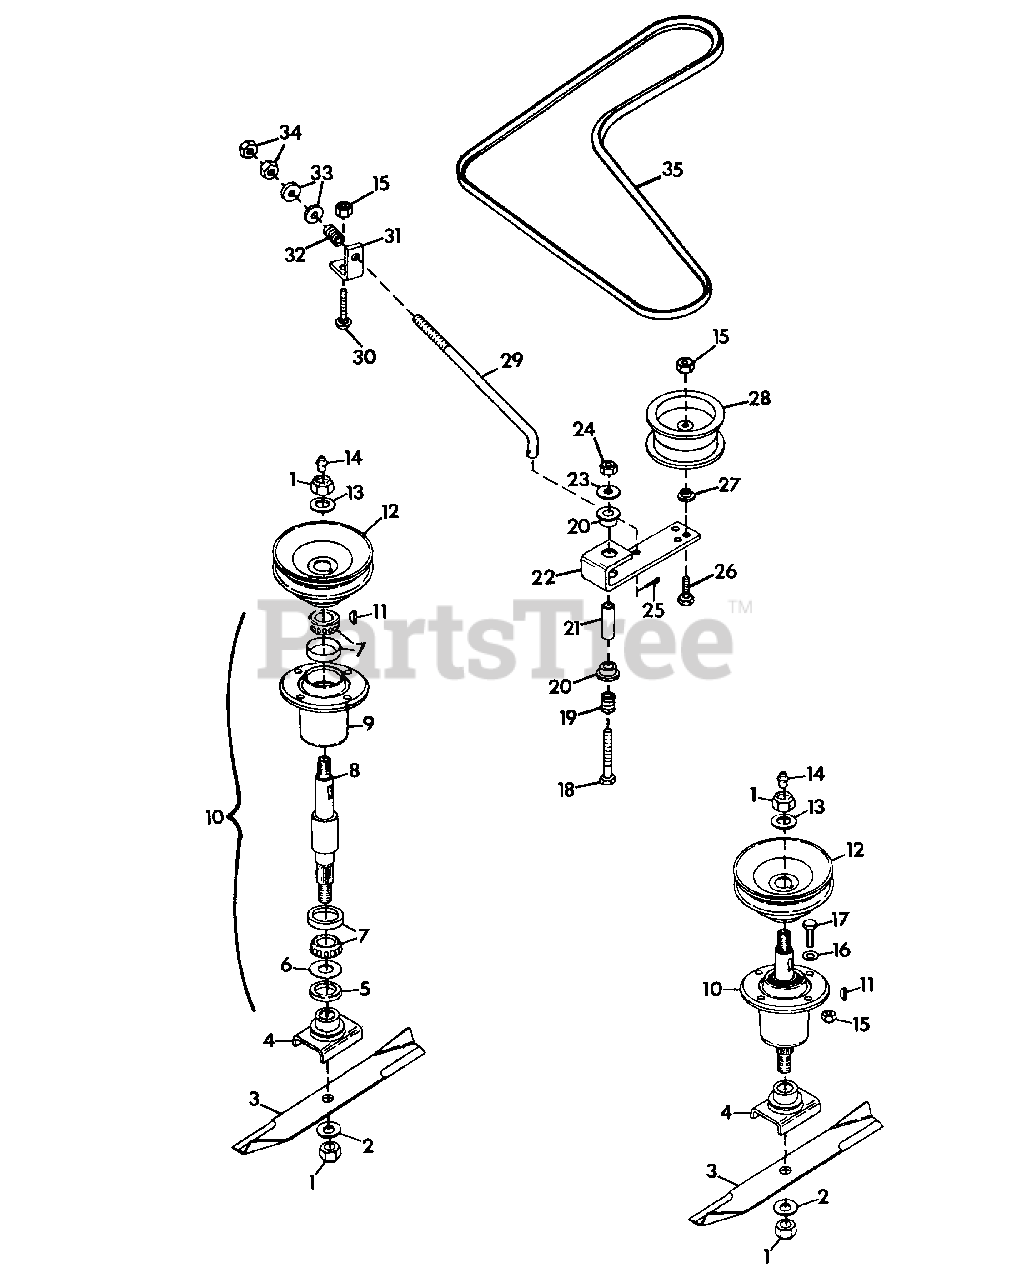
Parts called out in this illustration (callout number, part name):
1	NUT, LOCK 5/8-11
2	WASHER, FLAT .656X1.312X.095
3	BLADE
4	WELDMENT, BLADE CRADLE
5	SEAL, STEEL
6	WASHER, FLAT .975X1.970X.030
7	ASSEMBLY, BEARING
8	SHAFT, SPINDLE
9	HOUSING, BEARING
10	ASSEMBLY, SPINDLE
11	KEY, WOODRUFF 1/4X1 HARD #15
12	SHEAVE, SPINDLE
13	WASHER, FLAT .687X1.312X.122
14	FITTING, LUBE 1/8 NPT
15	NUT, LOCK 3/8-16
16	WASHER, FLAT .438X1.00X.083
17	BOLT, HEX 3/8-16X1.250
18	BOLT, HEX 1/2-13X3.25
19	SPRING, COMPRESSION 1X.80X36 LB/N
20	BUSHING, NYLON .760X1.00X.600
21	SPACER
22	ARM, IDLER PIVOT
23	WASHER, FLAT .531X1.250X.100
24	NUT, LOCK 1/2-13
25	PIN, COTTER .09X.75
26	BOLT, HEX 3/8-16X2.25
27	BUSHING
28	PULLEY, IDLER
29	ROD, IDLER
30	BOLT, 3/8-16X1.00 RD HD SQ NK
31	BRACKET, BELT TENSIONER
32	SPRING, COMPRESSION 1.00X.78
33	WASHER, FLAT .406X.812X.065
34	NUT, HEX 3/8-24
35	BELT, PRO-40 MOWER
